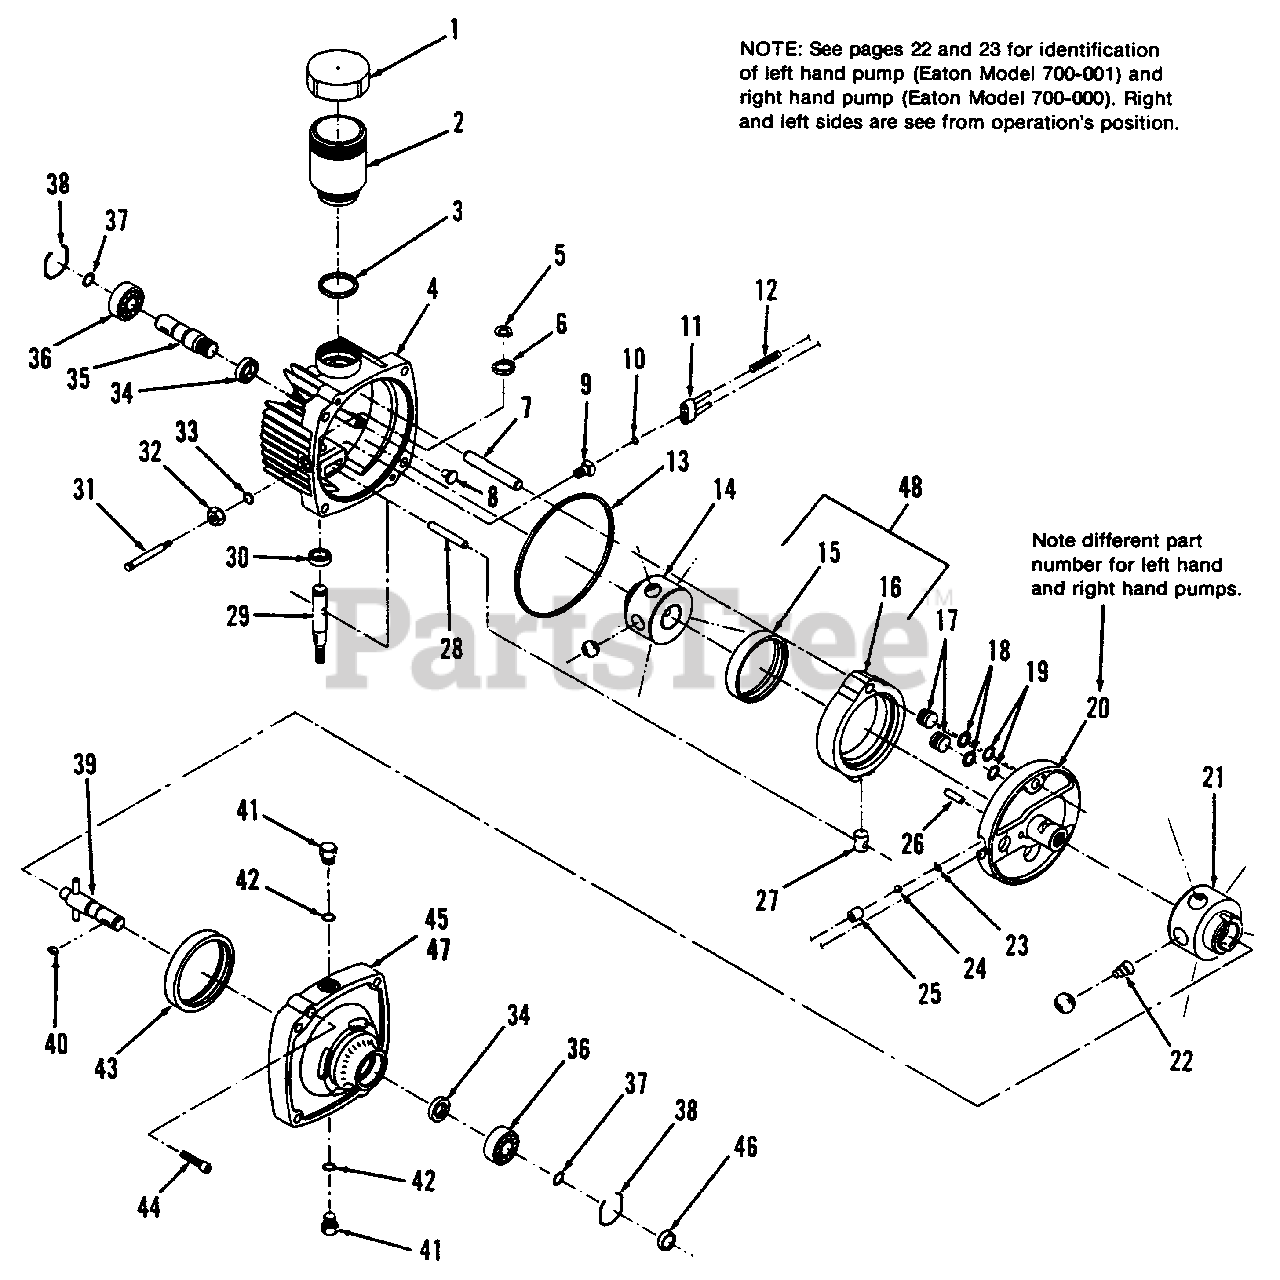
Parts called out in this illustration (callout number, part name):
1	RESERVOIR COVER, Sub-Assy.
2	RESERVOIR BODY
3	SEAL RING, Square Cut
4	COVER, Service Kit (Includes Ref. Nos. 5, 6, 7, 28, 29, 30 & 34)
5	RING, External Retaining
6	WASHER, Control Shaft
9	FITTING GUIDE, O-Ring, S.A.
10	O-RING
11	BRACKET, Pins, Sub-Assy.
12	SPRING, Valve
13	SEAL RING, Square Cut
14	PUMP ROTOR, Ball, Sub-Assy.
20	PINTLE, Sub-Assy. (Used on RH Eaton Pump - Model 700-000) (Incl. Ref. Nos.17, 18, 19, 23, 24, 25, 26)
20	PINTLE, Sub-Assy. (Used on LH Eaton Pump - Model 700-001) (Incl. Ref. Nos. 17, 18,19, 23, 24, 25, 26)
21	MOTOR ROTOR, Ball, Sub-Assy. (Includes Qty. 5 of Ref. No. 22)
22	SPRING, Piston
27	CAM RING, Insert
31	SHAFT, Dump Valve
32	NUT, Gasket, Sub-Assy.
33	O-RING
34	SEAL, Oil
35	SHAFT, Input
36	BEARING, Ball (Input)
38	RING, Retaining
39	OUTPUT SHAFT, Sub-Assy.
40	* KEY, Woodruff
41	O-RING, Sub Assy.
42	TUBE FITTING, O-Ring
44	CAPSCREW, Socket Hd.
47	BODY, Sub-Assy. (Includes Ref. Nos. 34, 36, 37,38,39,43&45)
48	CAM RING, Sub-Assy. (Incl. Ref. Nos. 15 & 16)
